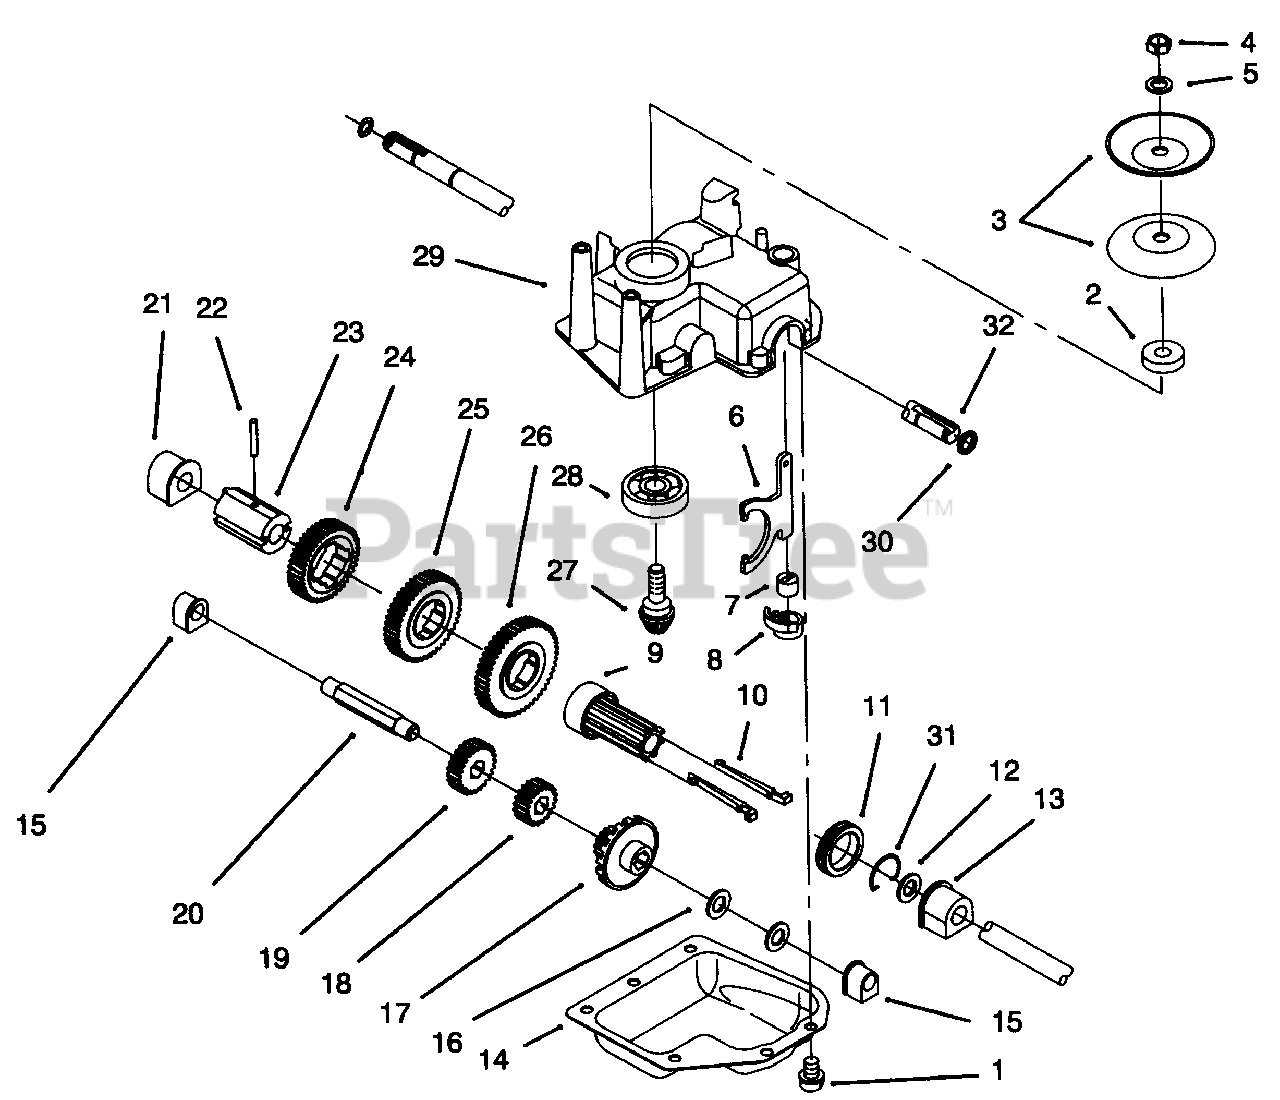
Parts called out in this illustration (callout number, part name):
1	Screw-Self Tapping
3	Pulley-Half
4	Locknut
5	Washer-Flat
6	Yoke-Shift
7	Bushing-Yoke
8	Retainer-Shift Fork
9	Sleeve-Shift Key
10	Key-Shift
11	Collar-Shift
12	Washer-Thrust
13	Bushing-Output Shaft
14	Cover-Gear Case
15	Bushing-Int. Shaft
16	Washer-Thrust
17	Gear-Pinion 15 Tooth
18	Gear-Pinion 20 Tooth
19	Gear-Pinion
20	Shaft-Intermediate
21	Bushing-Output Shaft
23	Sleeve-Gear
24	Gear-39 Tooth 3rd Gear
25	Gear-44 Tooth 2nd Gear
26	Gear-49 Tooth 1st Gear
27	Pinion-Bevel
28	Bearing-Ball
29	Gear Case-Upper
31	Clip-Spring
32	Shaft-Output
